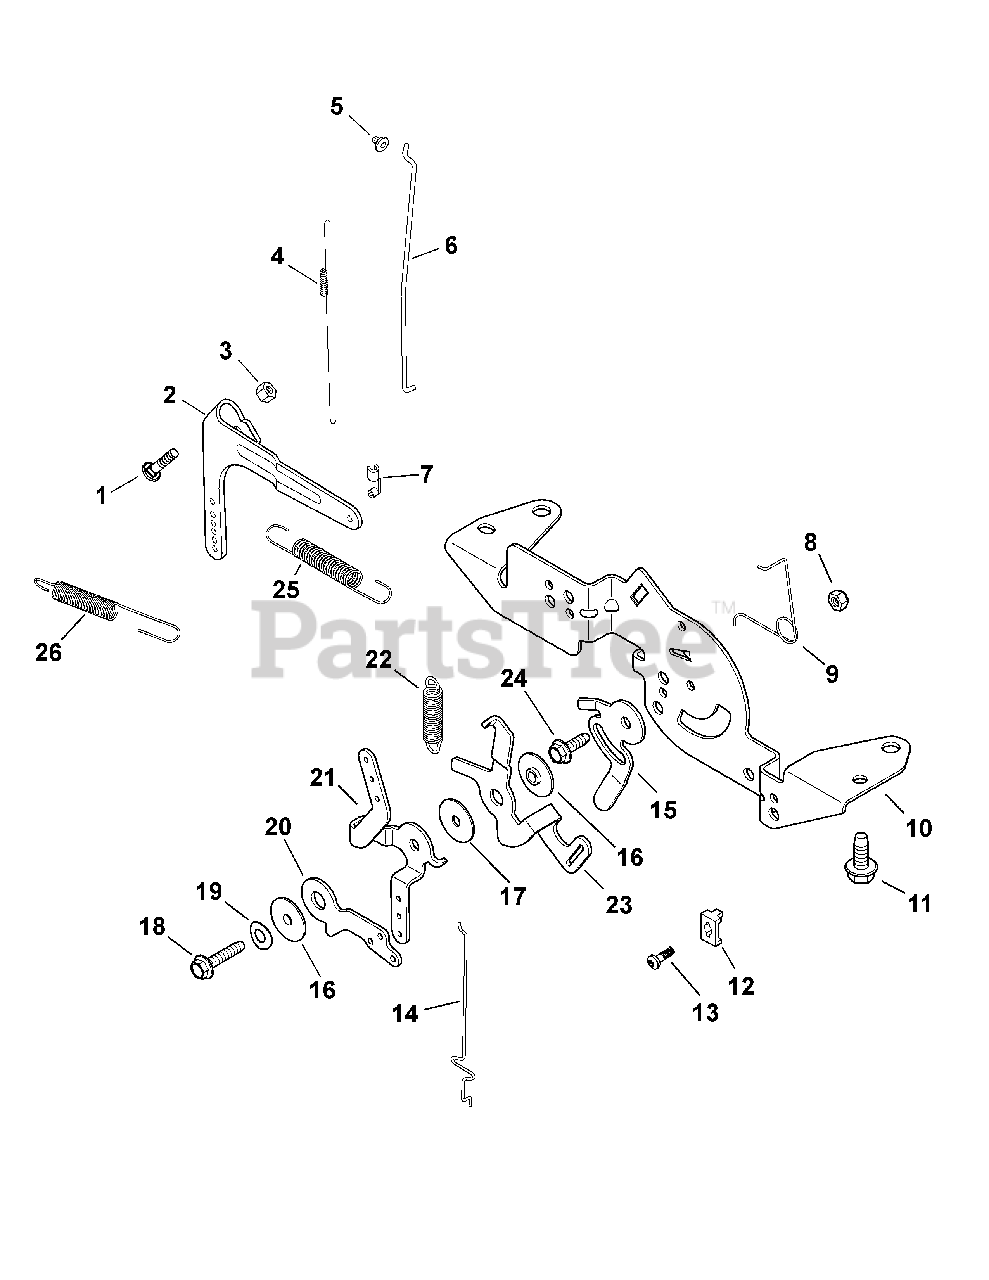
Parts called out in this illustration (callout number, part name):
1	Rd. Hd. Sq. Neck Bolt, M6 x 1.0 x 25
2	Governor Lever
3	Flg. Nut, M6 x 1.0
4	Linkage Spring
5	Linkage Retaining Bushing
6	Throttle Linkage
7	Throttle Linkage Bushing
8	Lock Nut, M5 x .8
9	Choke Return Spring
10	Control Bracket
11	Flg. Thd. Frm. Screw, M6 x 1.0 x 16
12	Cable Clamp
13	Lbd. Thd. Frm. Screw, M5 x 0.8 x 16
14	Choke Linkage
15	Speed Setting Lever
16	Control Assembly Spacer
17	Flat Washer, 5.5MM
18	Thd. Frm. Screw, M5 x 0.8 x 25MM
19	Spring Washer, 1/4"
20	Choke Lever
21	Speed Control Lever
22	Speed Control Spring
23	Governor Spring Lever
24	Flg. Thd. Frm. Screw, M5 x 0.8 x 16
25	Governor Spring
26	Governor Spring
